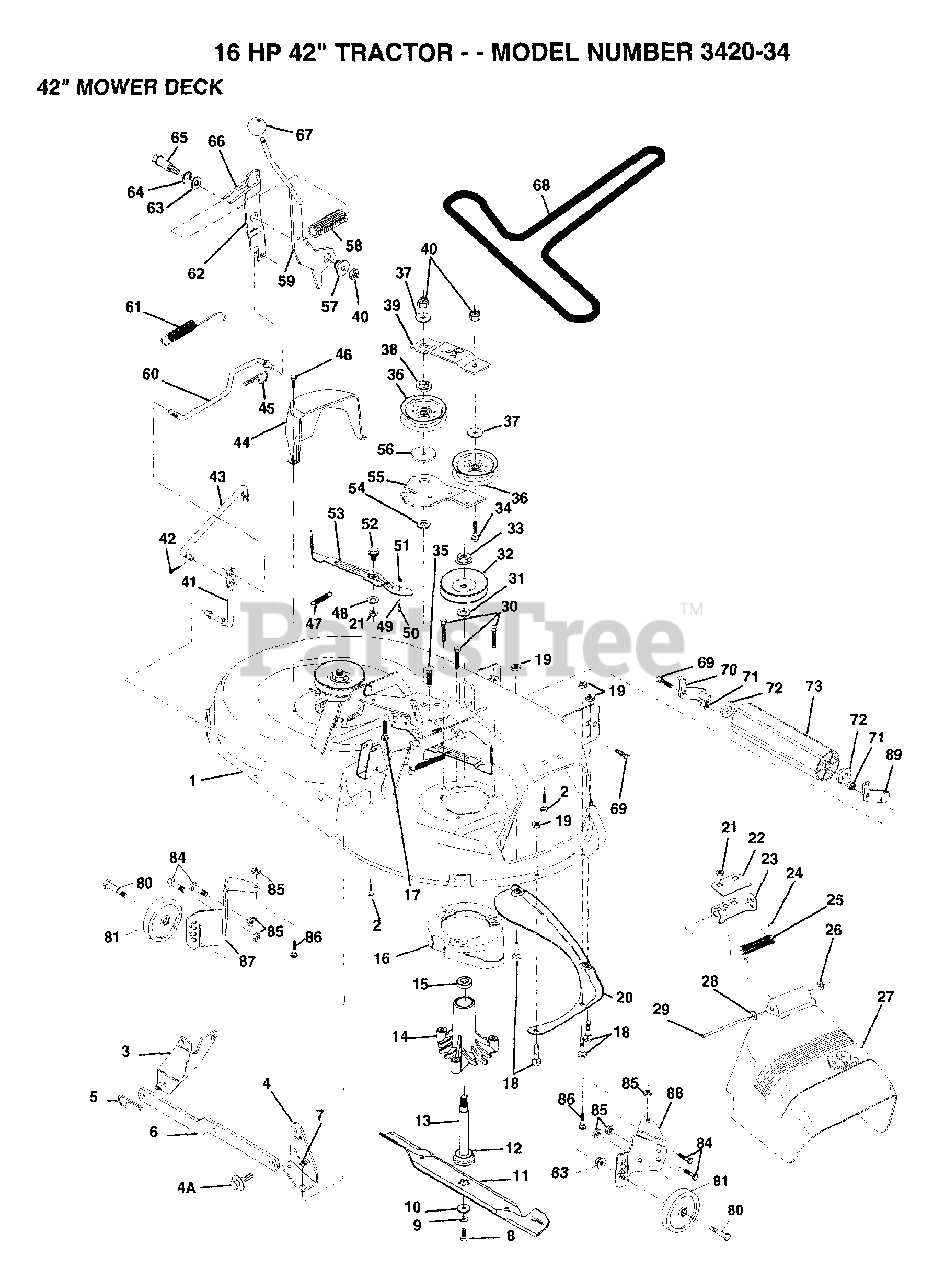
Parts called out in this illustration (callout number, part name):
2	BOLT
3	BRKT ASM SWAY BAR
4	BRKT DECK SW BAR
4A	BOLT SHD 5/16-18
7	NUT
8	BLADE BOLT
10	WASHER BLADE
11	"BLADE.42"" HIPERF"
12	BEARING.BALL
14	HSG ASM MANDREL
15	BEARING
17	BOLT CARRIAGE
18	BOLT
19	NUT
22	STIFFENER BRKT
23	DEFLECTOR BRKT
24	CAP-SLEEVE LT
25	SPRING TORSION
26	NUT PUSH M
27	DEFLECTOR.SHIELD
28	WASHER
29	HINGE ROD
31	WASHER
34	BOLT
35	XMAS TREE FASTNER
36	FLAT IDLER PULLEY
37	WASHER GT
38	RETAINER SPACER
39	IDLER ARM STIFF
41	PIVOT ROD
43	CLUTCH ROD SECOND
45	RETAINER M
46	SCREW LT
47	SPRING EXTENSION
48	HARD SMALL WASHER
50	SHOULDER BOLT
51	LOCKNUT
53	BRAKE PAD ARM ASM
54	HARDENED WASHER
55	IDLER ARM
56	SPACER RETAINER
57	BUSHING
59	LEVER.ASM.CLUTCH
60	"ROD, CLUTCH PRIM"
61	RETURN SPRING
62	CLUTCH ARM SECOND
63	WASHER
64	RING
65	SHOULDER BOLT
66	SPRING KEEPER
68	BELT-V.92.4.MWR
69	BOLT
72	WASHER
80	BOLT M
81	WHEEL.GAGE.BLK.PL
83	NUT
84	BOLT
